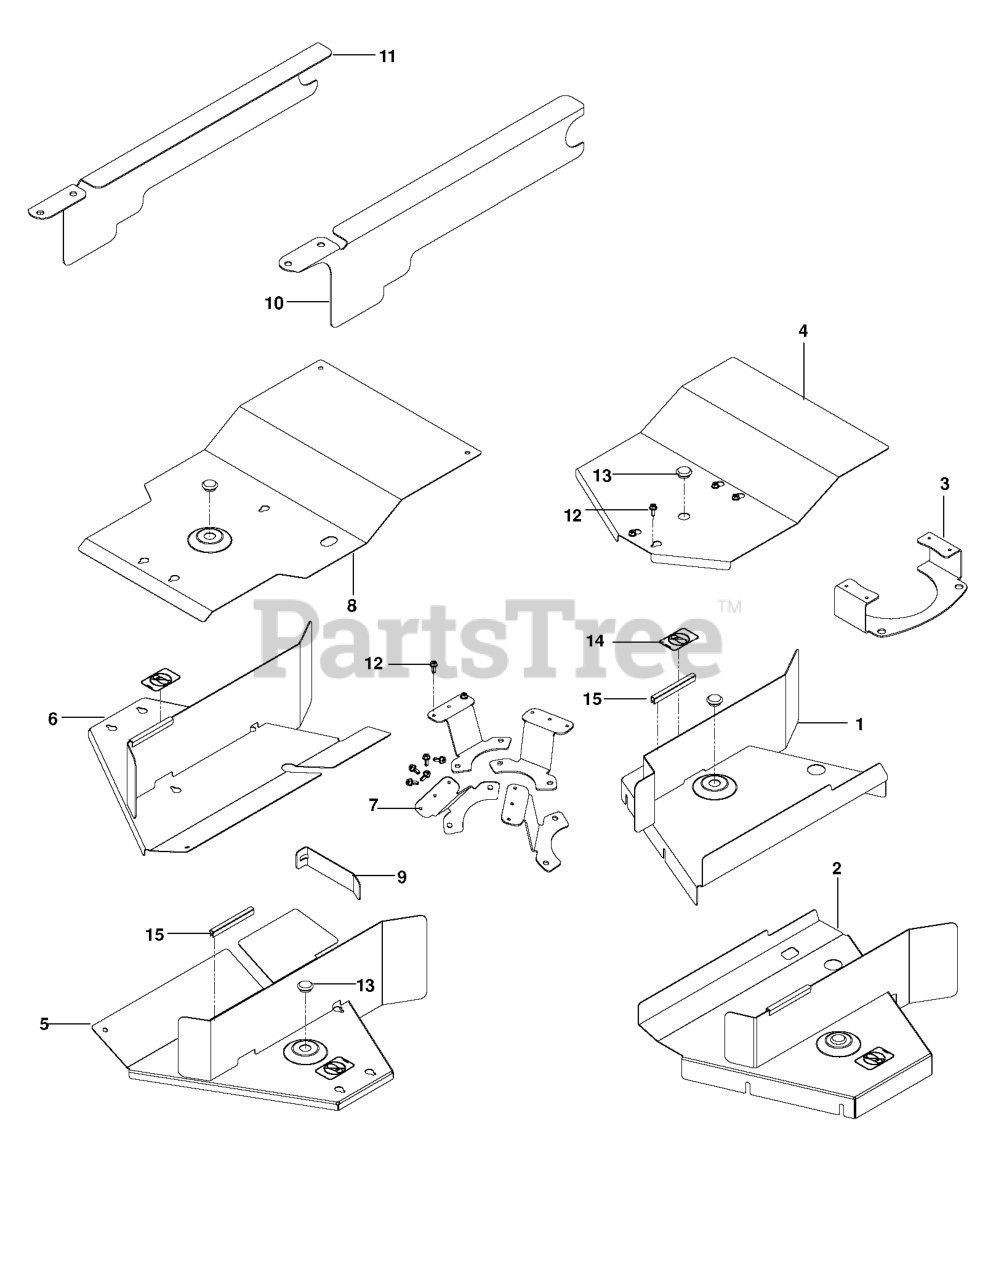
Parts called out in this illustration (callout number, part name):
1	WELDMENT.LEFT.PZ.G60.BLACK
2	WELDMENT.RIGHT.PZ.G60.BLACK
3	BRACKET GUARD.PZG.BLK
4	GUARD.CENTER.PZ.G60.BL
5	WLDMNT, LEFT COMBI 61, BLK
6	WLDMNT, RIGHT COMBI 61, BLK
7	BRACKET,BELT CVR,COMBI BLK
8	GUARD.CENTER.COMBI.61.BLACK
9	GUARD, COMBI STRUT, BLK
10	SKIRT.RH.BLK
11	SKIRT.LH.BLK
12	SCREW.1/4-20X5/8
13	PLUG, BUTTON HOLE
14	DECAL, NO STEP
15	RP.FLEX TRIM, BLK-LENGTH 1 FT
